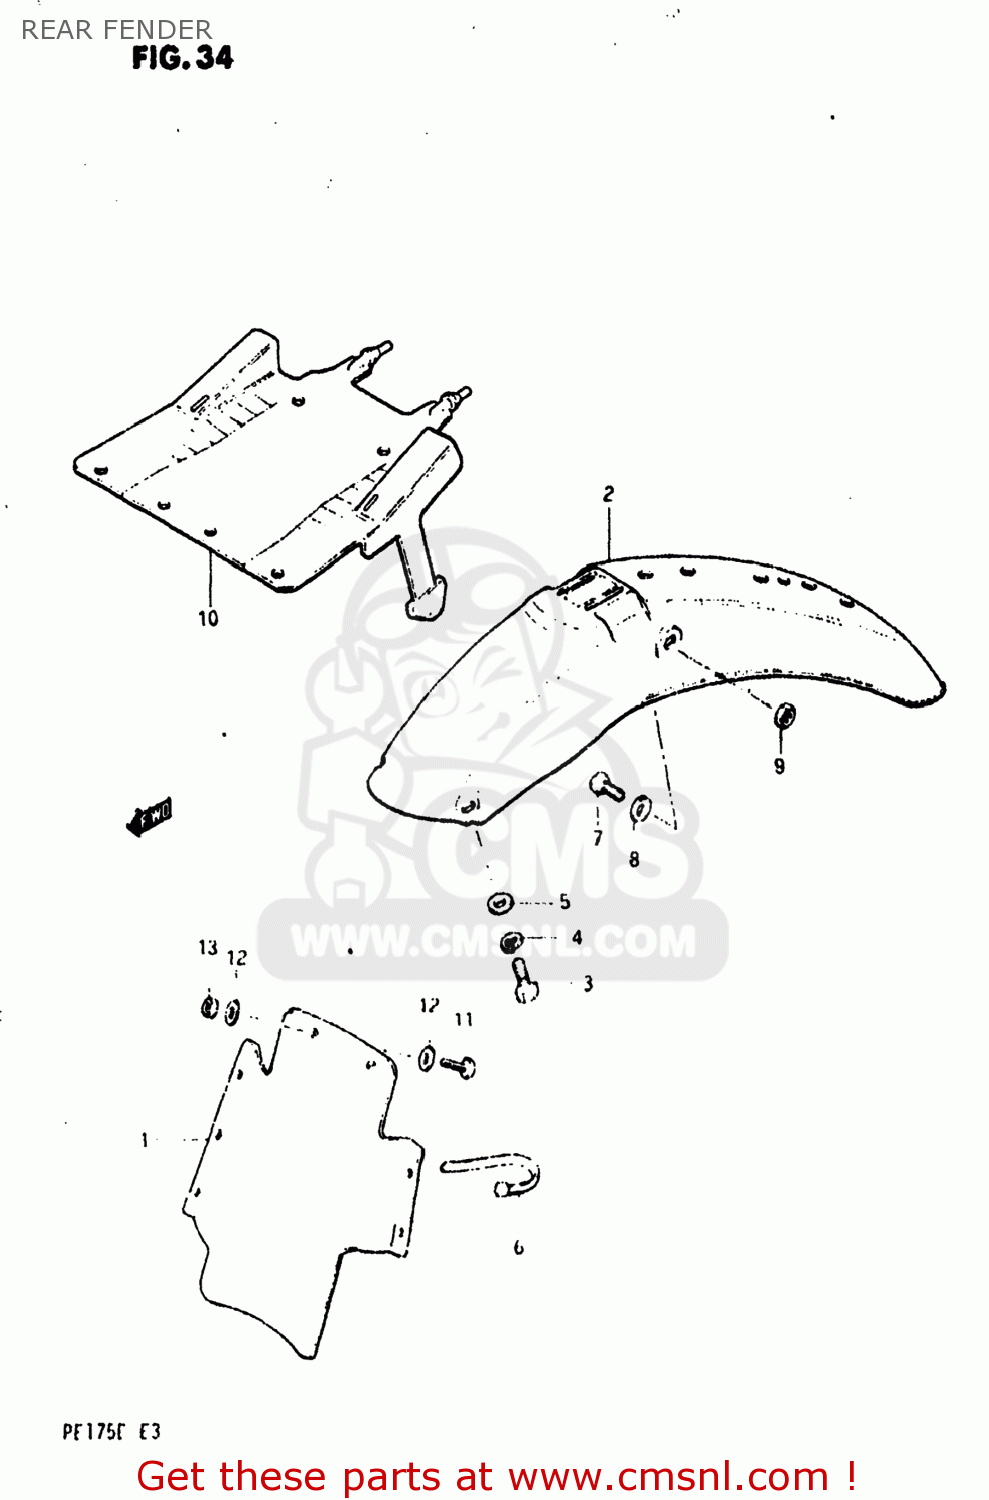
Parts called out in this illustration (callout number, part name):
1	FENDER,RR FR
2	FENDER,REAR
3	BOLT, UPPER
4	LOCK WASHER
5	WASHER
6	CLAMP
7	SCREW
8	WASHER
9	NUT
10	GUIDE,RR FENDER MUD
11	SCREW
12	WASHER
13	NUT
